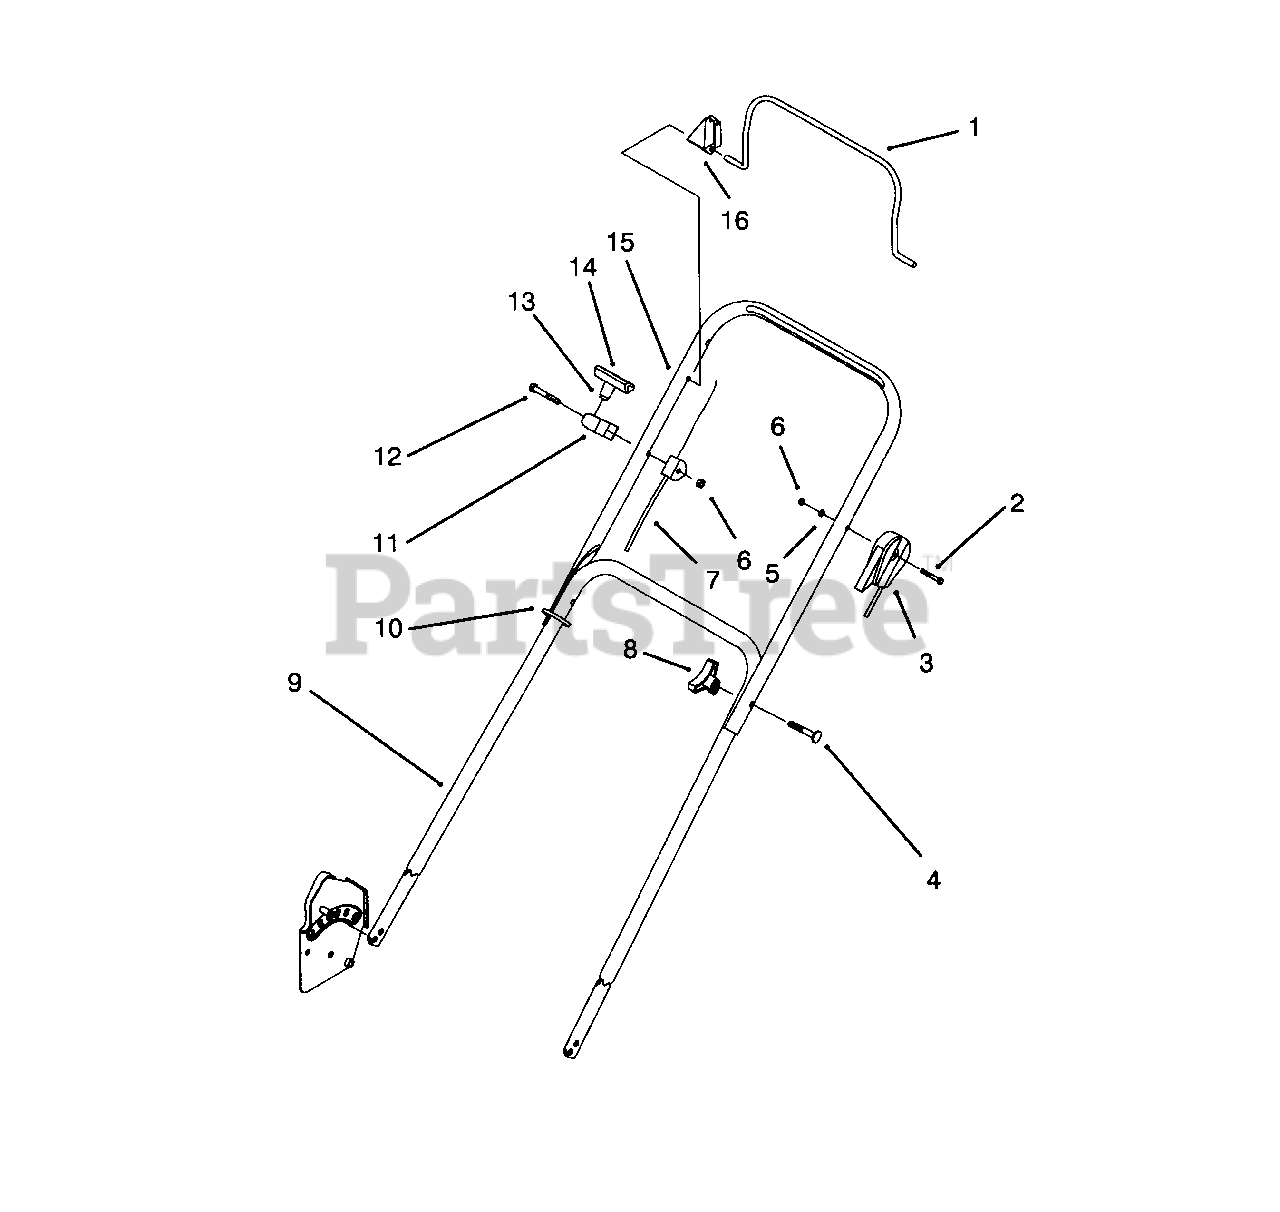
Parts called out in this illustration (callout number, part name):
1	Bail-Flywheel Brake
2	Screw-Hex Hd. Cap
3	Cable-Throttle
4	Screw-Handle
5	Washer
6	Nut-Lock
7	Cable-Flywheel Brake
8	Knob
9	Handle-Lower
10	Tie-Cable
11	Guide-Rope
12	Screw-Hex Hd. Cap
13	Handle-Starter
14	Clip-Rope Insert
15	Handle-Upper
16	Stop-Pivot
